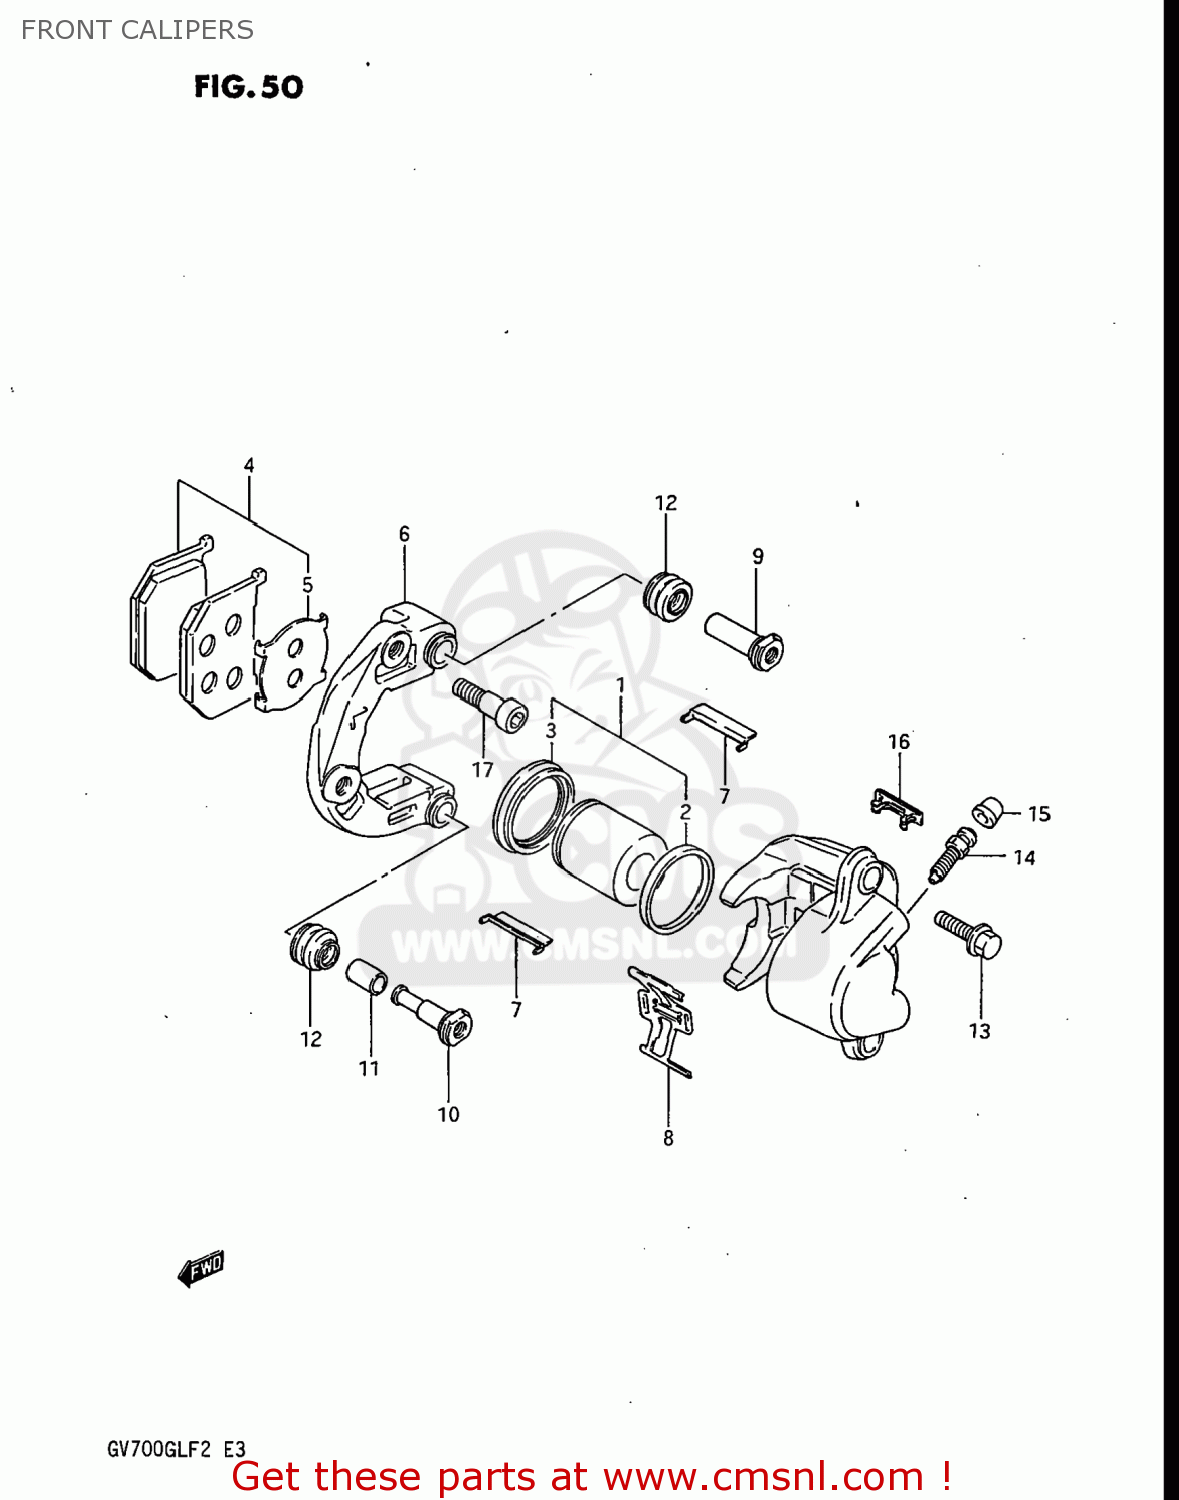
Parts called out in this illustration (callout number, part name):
1	PISTON SET
2	SEAL,PISTON
3	BOOT,PISTON
4	PAD SET
5	SHIM,PAD
6	COVER,CALIPER
7	GUIDE,PAD
8	SPRING,PAD
9	AXLE NO.1
10	AXLE NO.2
11	BUSH,AXLE
12	BOOT,AXLE
13	BOLT
14	BLEEDER
15	CAP,BREATHER
16	COVER
17	BOLT
